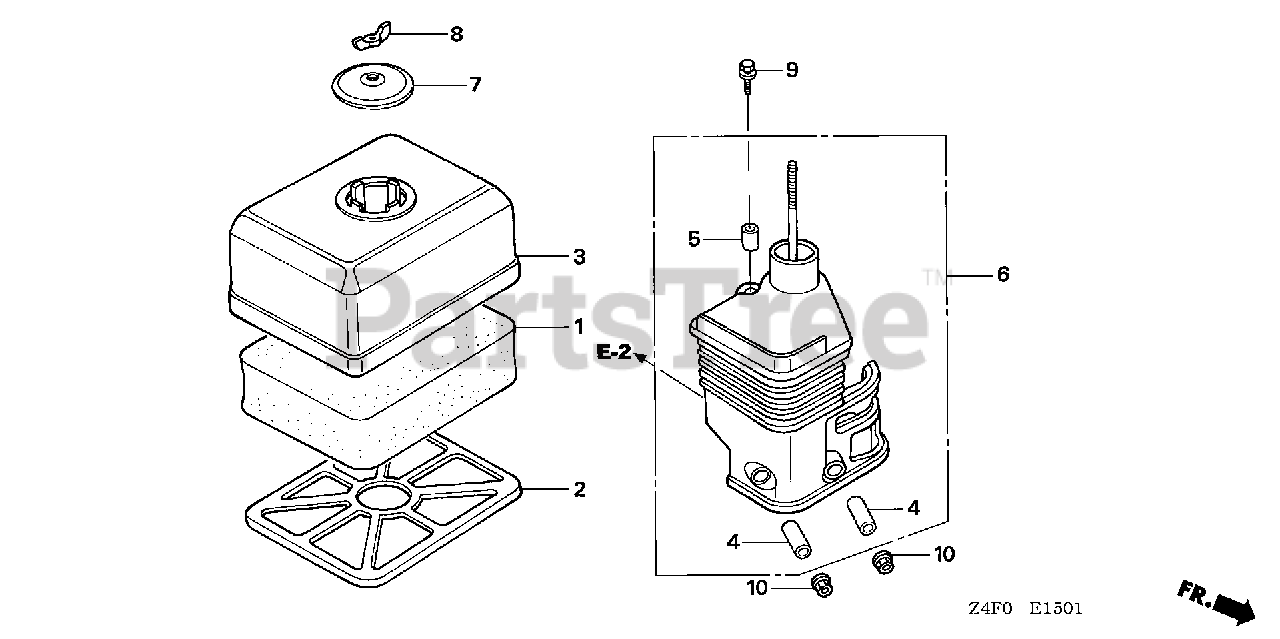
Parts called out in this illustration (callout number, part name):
1	ELEMENT, AIR CLEANER (SEMI-DRY)
2	GRID, AIR CLEANER (SEMI-DRY)
3	COVER, AIR CLEANER (SEMI-DRY)
4	COLLAR, AIR CLEANER
5	COLLAR B, AIR CLEANER
6	ELBOW, AIR CLEANER
7	CAP, CLEANER
8	NUT, TOOL BOX SETTING
9	BOLT, FLANGE (6X20)
10	NUT, FLANGE (6MM)
